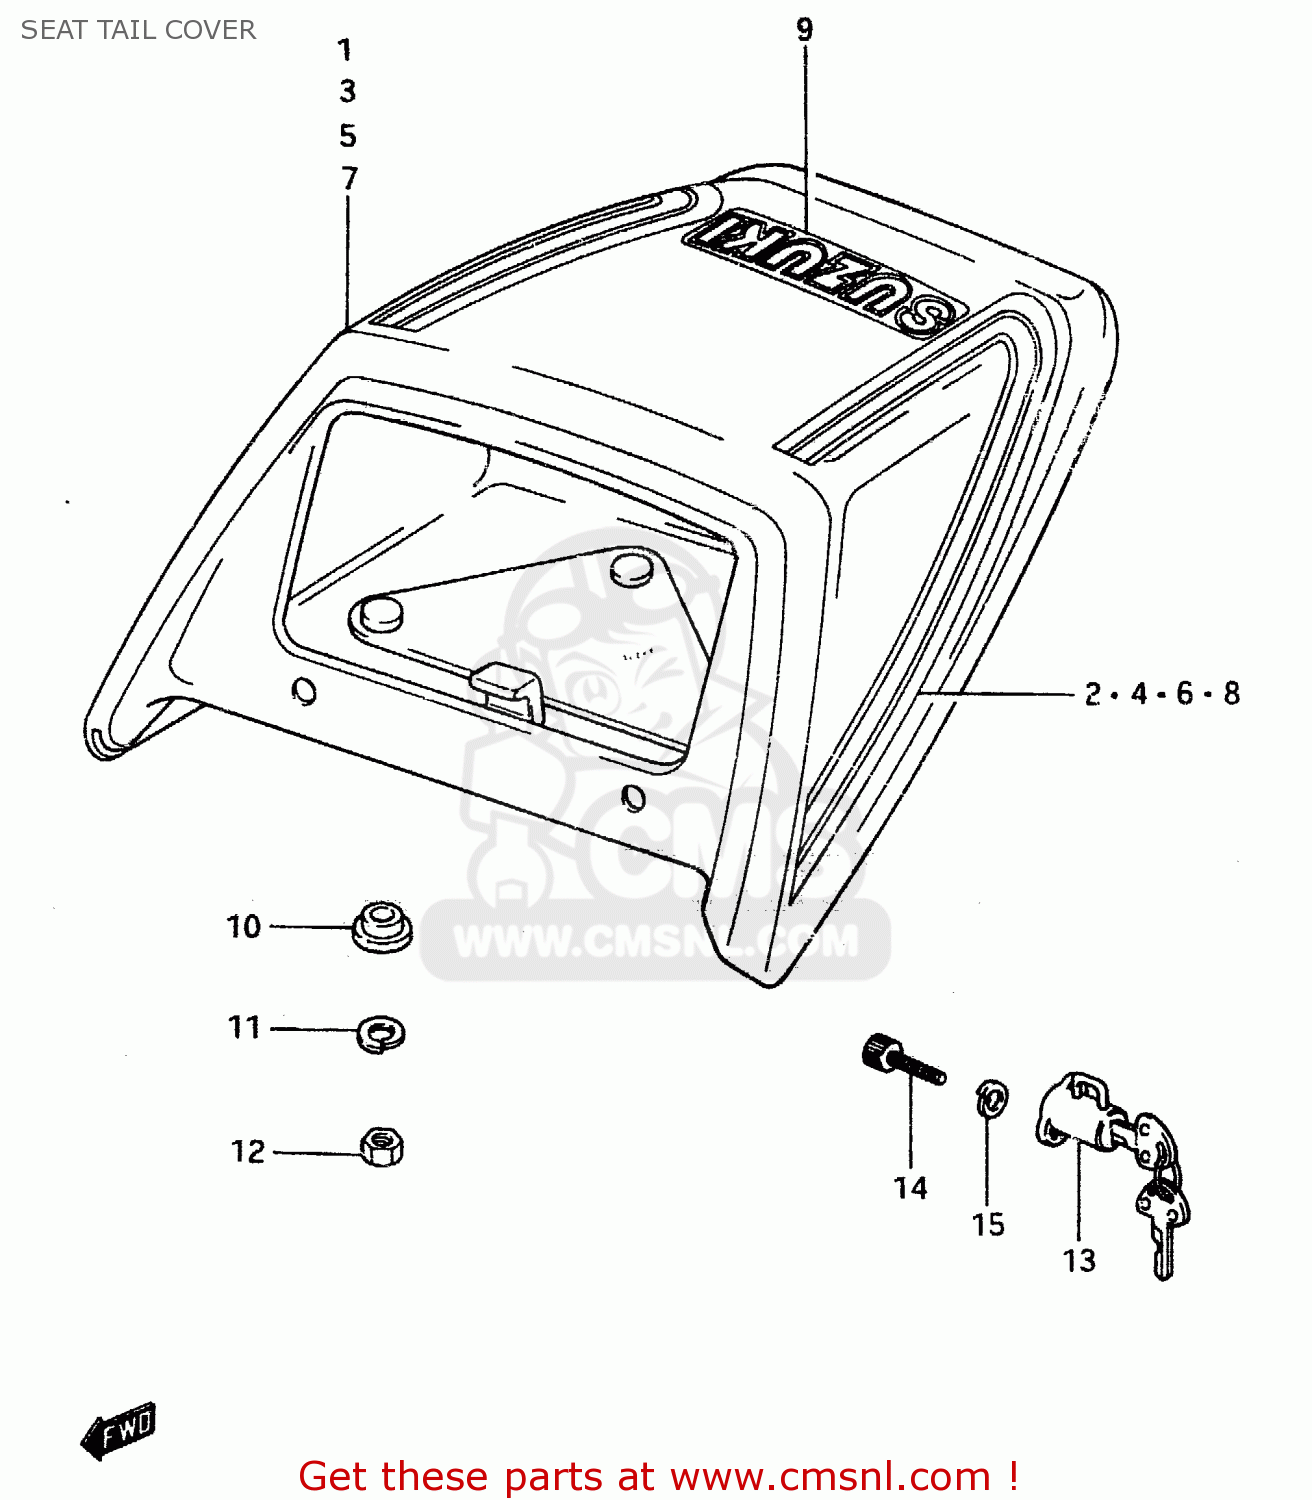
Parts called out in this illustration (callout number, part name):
1	COVER, SEAT TAIL (BLACK)
2	TAPE SET
3	COVER, SEAT TAIL (BLUE)
4	TAPE SET
5	COVER, SEAT TAIL (RED)
6	TAPE SET
7	COVER, SEAT TAIL (WHITE)
8	TAPE SET
9	EMBLEM,SEAT TAIL COVER RR
10	WASHER
11	LOCK WASHER
12	NUT
13	LOCK ASSEMBLY,HELMET
14	BOLT 6X11
15	LOCK WASHER
